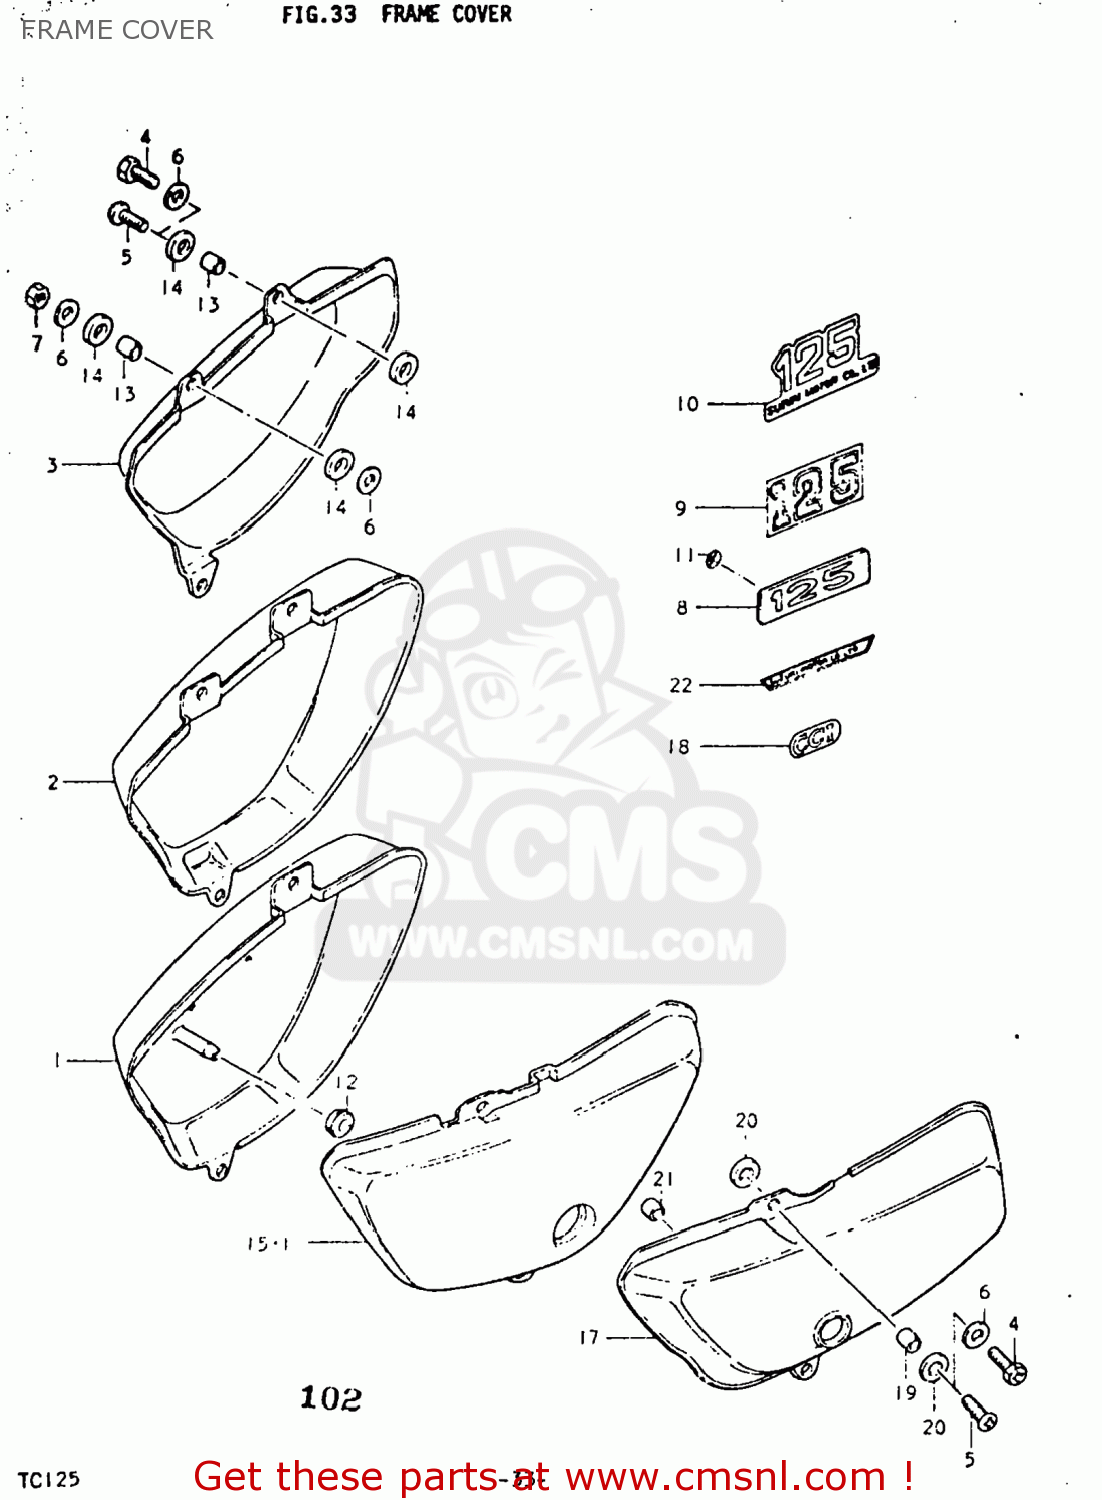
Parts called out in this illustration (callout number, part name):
1	COVER,FRAME,RIGHT
2	COVER,FRAME,RIGHT
3	COVER,FRAME,RIGHT
4	SCREW
5	SCREW
6	WASHER
7	NUT
8	EMBLEM,FRAME COVER
9	EMBLEM
10	EMBLEM
11	NUT
12	GROMMET
13	SPACER (6.1X8X9.5)
14	CUSHION
15	COVER,FRAME,LEFT
16	COVER,FRAME,LEFT
17	COVER,FRAME,LEFT
18	EMBLEM,CCIS
19	SPACER (6.1X8X9.5)
20	CUSHION
21	CUSHION
22	LABEL,COMPANY NAME
